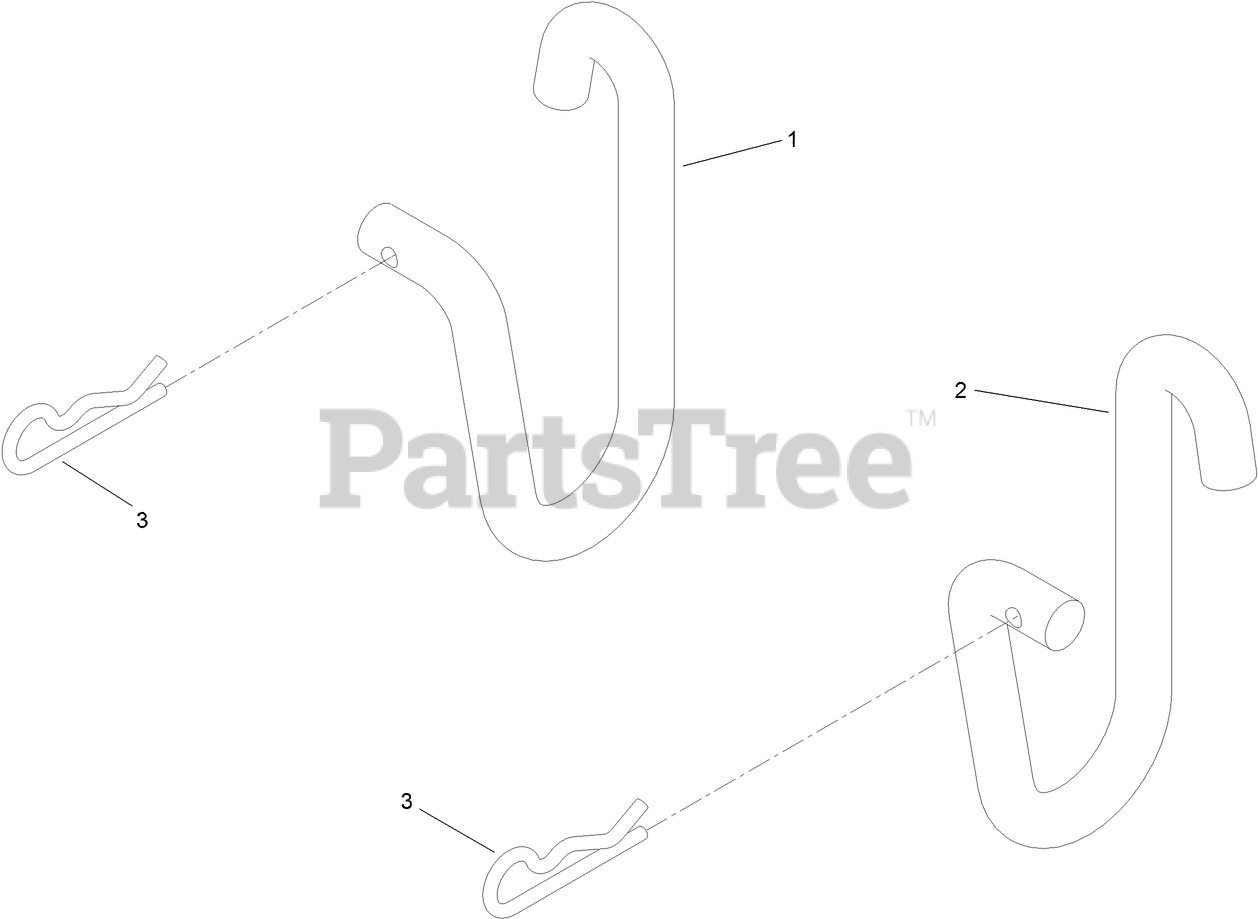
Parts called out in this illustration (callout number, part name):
1	LINK-RETENTION, DECK (RH)
2	LINK-RETENTION, DECK (LH)
3	PIN-COTTER
